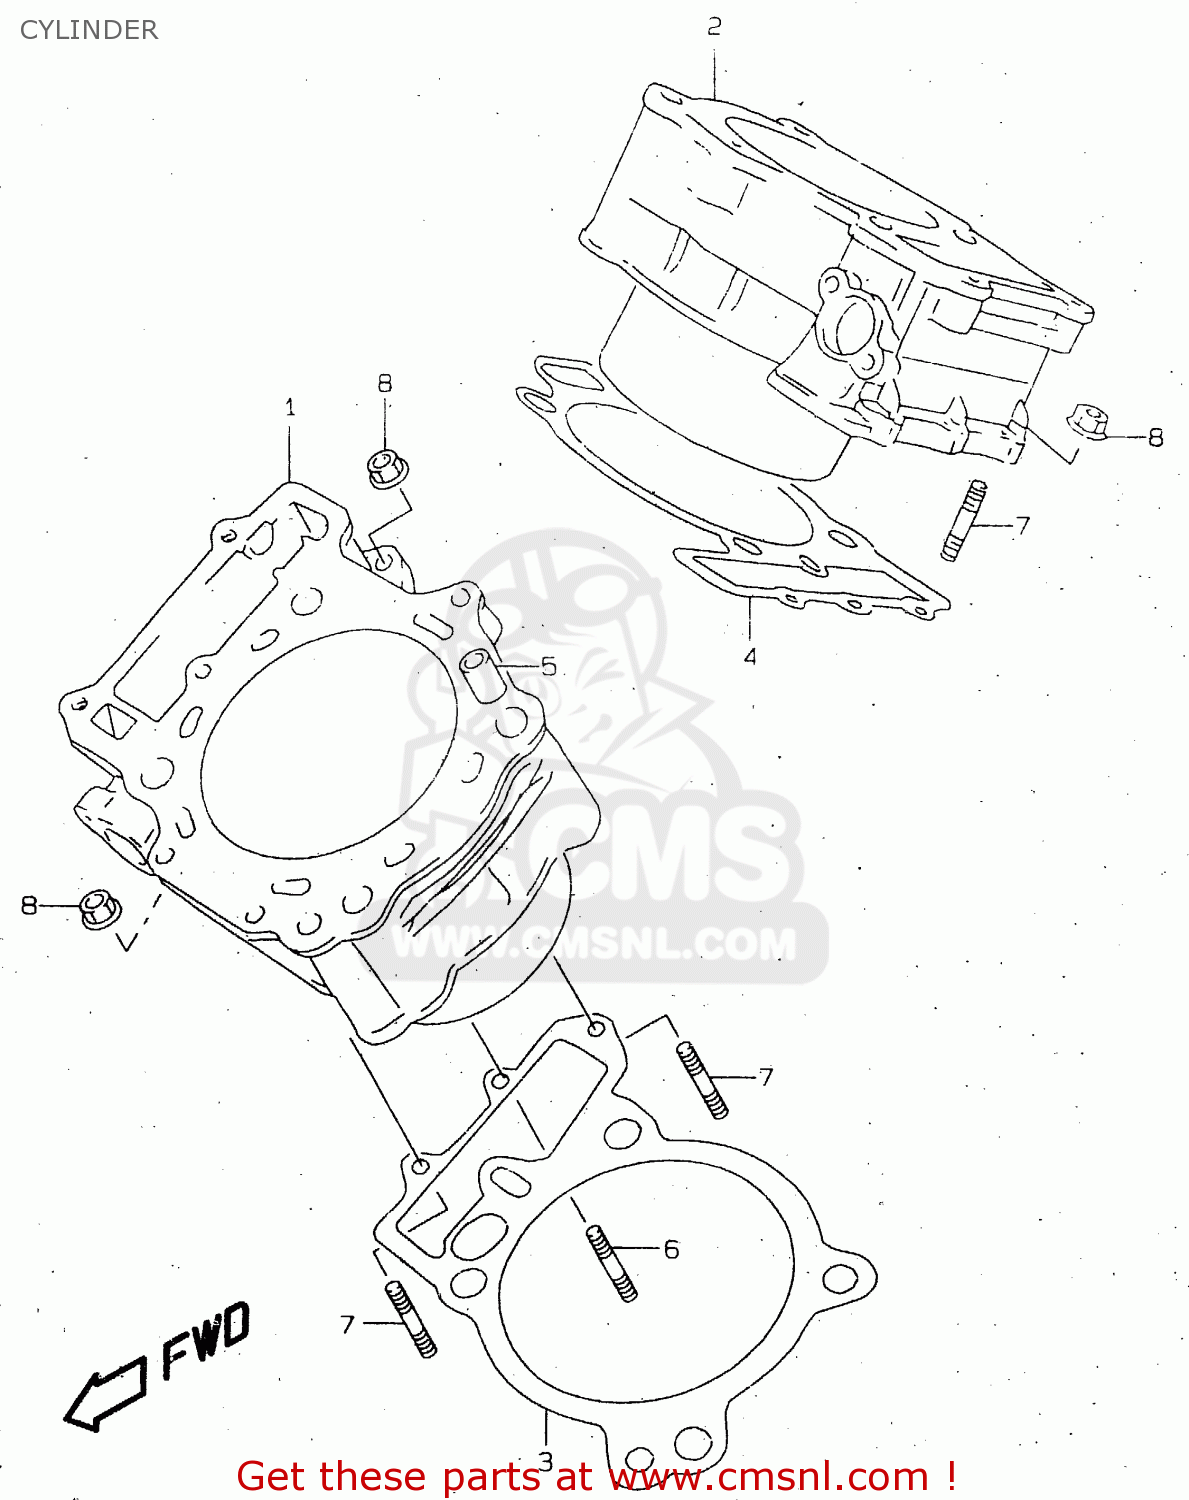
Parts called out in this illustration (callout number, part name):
1	CYLINDER,FRONT
2	CYLINDER,REAR
3	GASKET,CYLINDER FR (NAS)
4	GASKET,CYLINDER RR (NAS)
5	PIN
6	STUD BOLT (L:20)
7	STUD,M6X1X32
8	NUT
